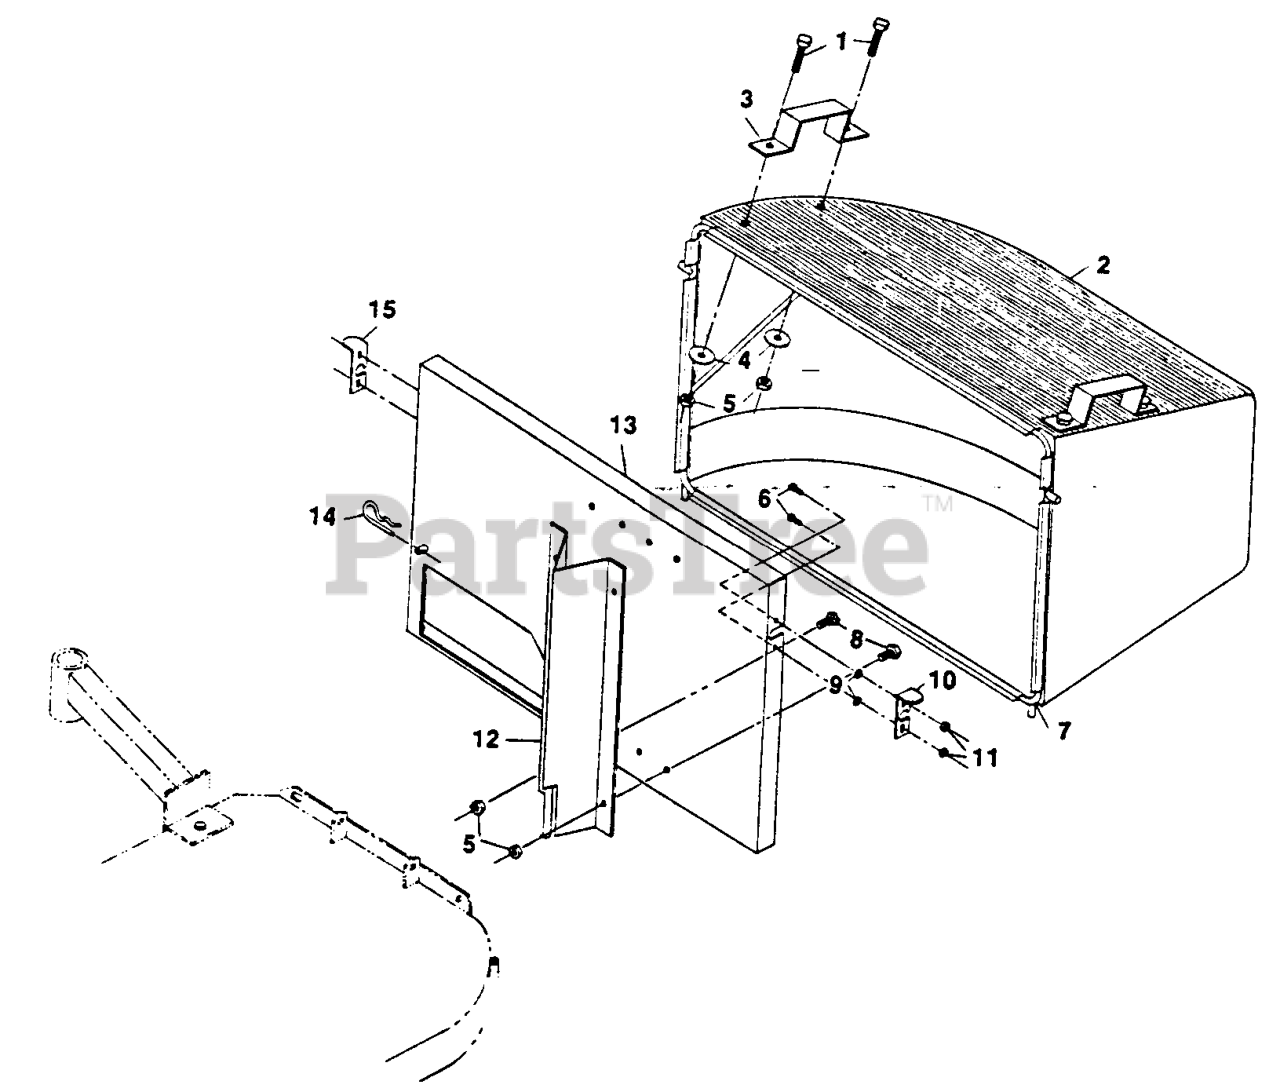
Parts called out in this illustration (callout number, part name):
7	FRAME-CATCHER
9	WASHER-SPRING
10	LATCH-CATCHER, RH
14	PIN-COTTER
15	LATCH-CATCHER, LH
